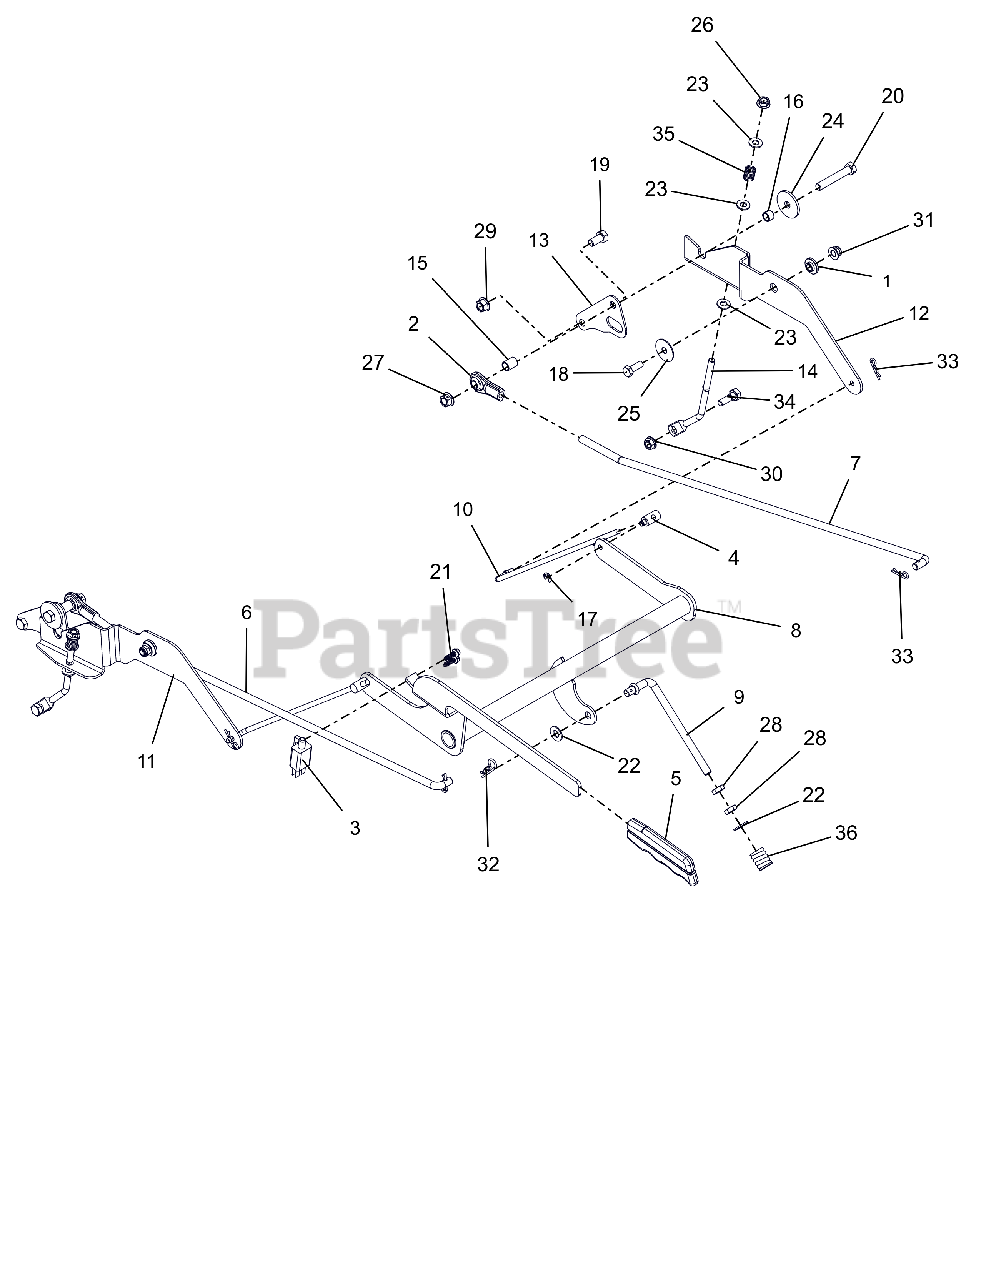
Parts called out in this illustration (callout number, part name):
1	BSHG, FLG .325X.499X.26X.88
2	ROD END, .38 RH
3	SWITCH- DOUBLE POLE N.O./N.O.
4	TRUNION, 1/4-20
5	GRIP, PARKING BRAKE (YELLOW)
6	STEERING, LINKAGE RH
7	STEERING, LINKAGE LH
8	WLDMT, BRAKE LEVER
9	LINK, OVER CENTER, PARKING BRK
10	LINK, BRAKE ARM
11	INTERLOCK, RH BRAKE LINK
12	INTERLOCK, LH BRAKE LINK
13	PLATE, TRANSAXLE ADAPTOR
14	LINK, BRAKE (XL)
15	SPCR, SLV .385X.500X.652
16	SPCR, SLV .385X.500X.350
17	RG-RTNG-EXT .250X.025
18	BOLT-HEX.31-18X.875 YWZC GR5
19	@BLT-HEX .38-16X.75 GR5 YWZC
20	@BLT-HEX .38-16X2.25 GR5 YWZC
21	SCR-TAP #12X.75 BOSS INDHXHD
22	@WSHR-FL-STL.406X.812X.065 YWZ
23	@WSHR-FL-STL.344X.688X.065YWZC
24	WSHR-FL-STL .380X1.50X.125YWZC
25	WSHR-FL-STL .347X1.254X.048YWZ
26	@NUT-LK-CTR-FLG .31-18 YZ GR F
27	NUT-LK-CTR-FLG .38-16 YWZC
28	NUT-HEX-JAM .375-16 YWZC
29	@NUT-LK-TOP-FLG .38-16 YWZC
30	@NUT-LK-TOP-FLG .31-18 YWZC
31	@NUT-LK-NYL-FLG .31-18 YWZC
32	PIN-HAIR CTR .09 X 1.50 YWZC
33	PIN-HAIR INT .08X.18X1.18 YWZC
34	BOLT,SHLDR .38X.25 -.31-18X.75
35	SPRING, COMPRESSION
36	SG-COMP .187X.56X1.62
